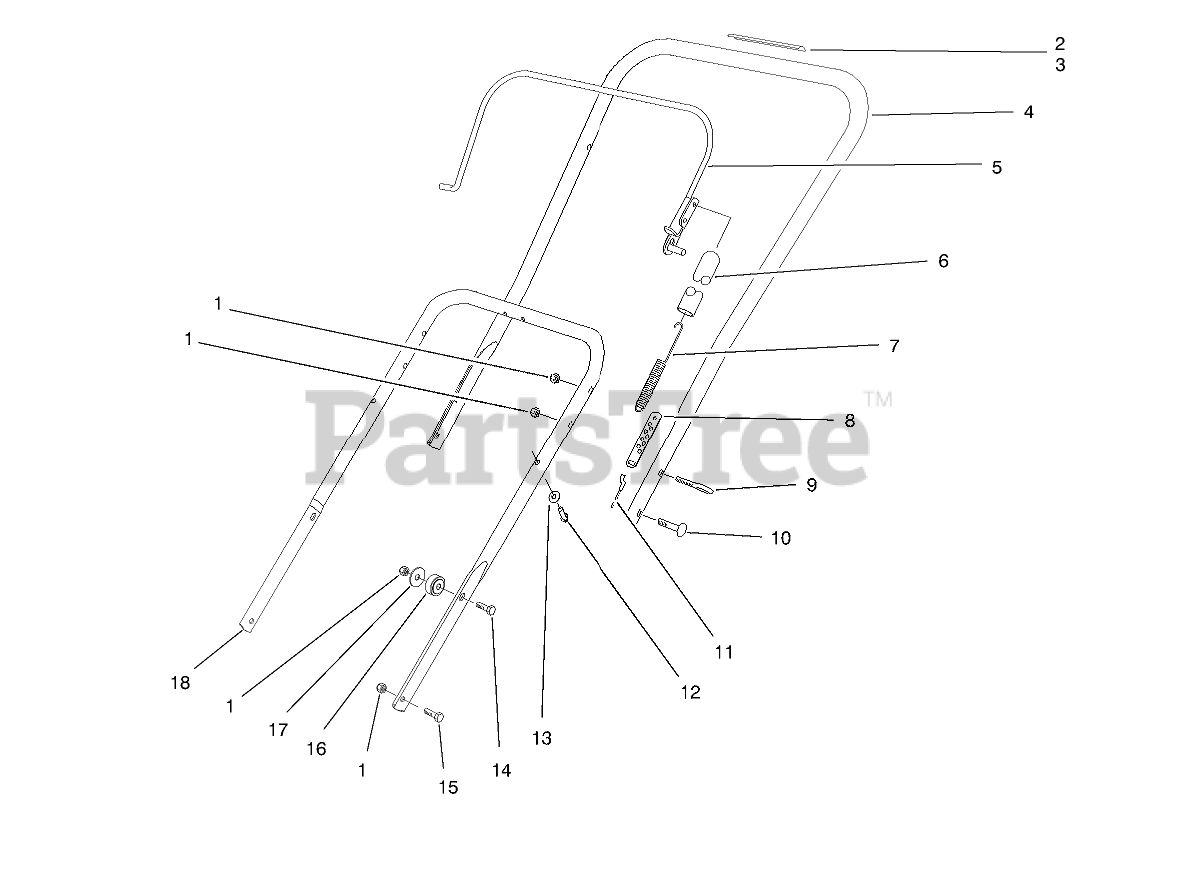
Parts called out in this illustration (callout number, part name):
1	NUT-LOCK, NI
2	DECAL - ROTOR DRIVE
3	DECAL-DRIVE, ROTOR
4	Handle-Upper
4	HANDLE-UPPER
4	UPPER HANDLE ASM
5	Bail
6	COVER-SPRING
7	SPRING-CLUTCH
8	ADJUSTER-CABLE
9	BOLT-EYE
10	SCREW
11	CABLE-CLUTCH
12	SCREW
13	WASHER
14	SCREW-HH
15	SCREW-HH
16	SPACER - LOWER HANDLE
17	WASHER-FLAT
18	Handle-Lower
